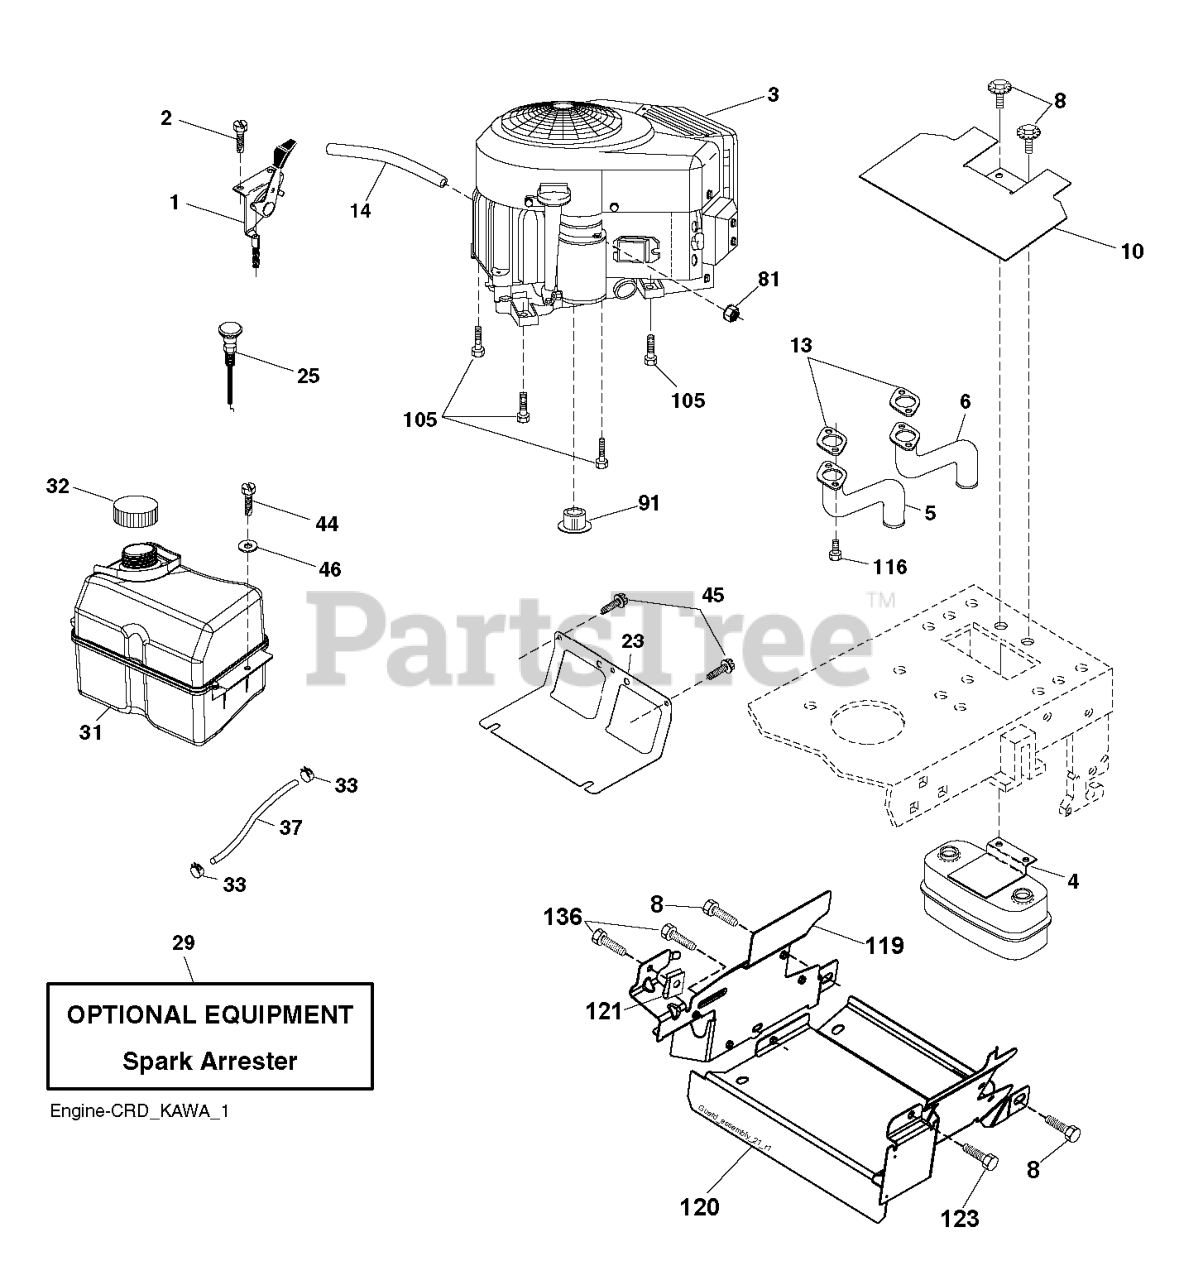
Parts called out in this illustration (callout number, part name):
1	CONTROL.THROTTLE.COBRA.BLACK
2	SCREW.#10 X 0.750.BOS
4	MUFFLER.TWIN.CYL.LOW.TONE
5	EXHAUST TUBE LH KAWI
6	EXHAUST TUBE RH KAWI
8	BOLT.5/16-18UNCX3/4 W/SEMS.BLK
10	RP SHIELD HEAT MUFFLER
14	TUBE, DRAIN OIL ASM.
23	SHIELD.BROWNING.DBR.GUARD
25	CONTROL.CHOKE.ERGO.PUSH-IN.BLA
29	KIT.SPARK ARRESTOR 794945 B&S
31	RP TANK FUEL FRT 1.5 GAL
32	CAP ASM.FUEL.2.25"FR.
33	HOSE CLAMP
37	LINE.FUEL.20
44	SCREW HEXWSHR 1/4-20X3/4
45	SCREW, 3/8-16X3/4
81	NUT
91	BUSHING.1.375OD
105	SCREW 3/8-16X1
116	NUT.HEX.FLANGE.TOPLOCK
119	LENKRAD
120	GUARD 532199767
123	SCREW, 5/16-18 X 1/2
136	SCREW.1/4-20X5/8
